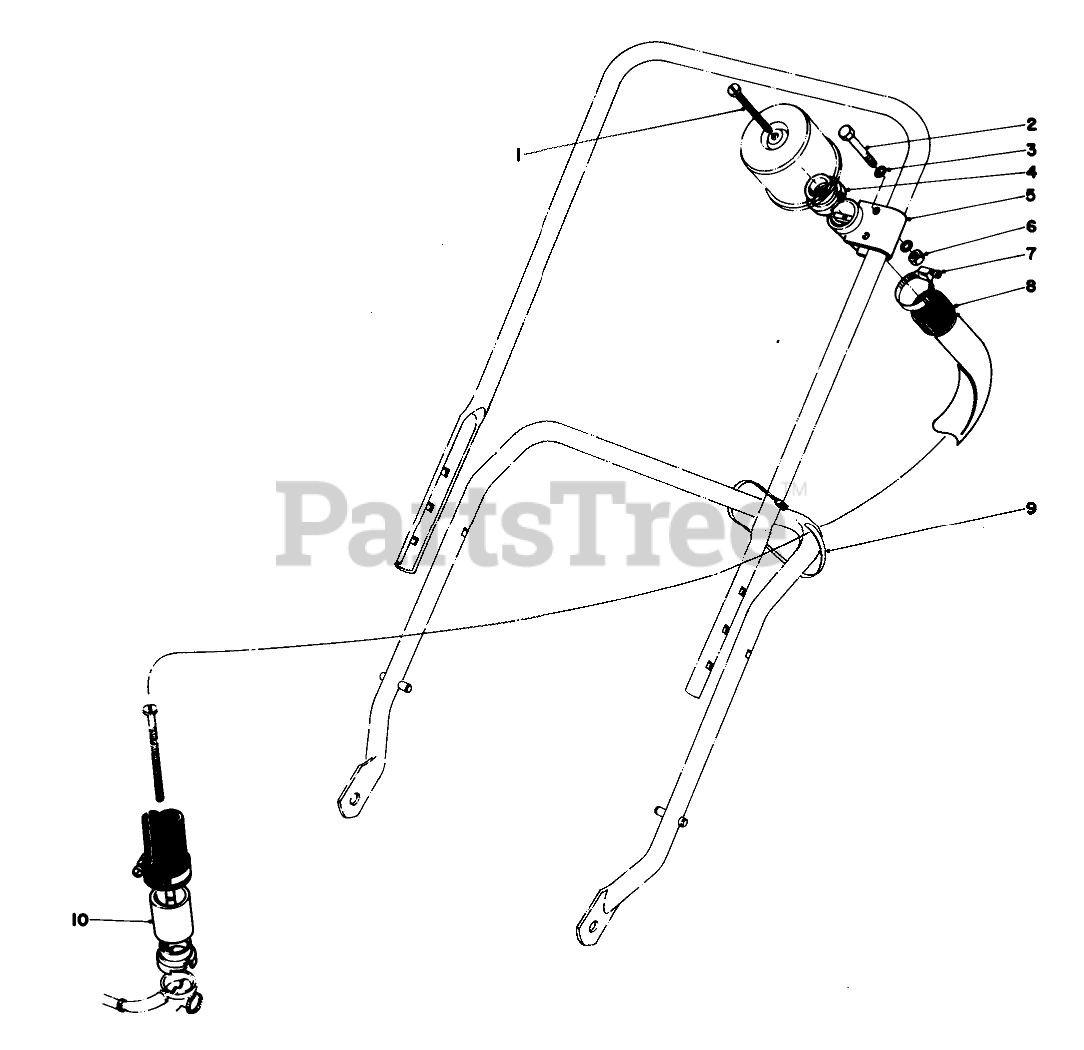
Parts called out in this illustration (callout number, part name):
1	Pan Hd. Machine Screw
2	SCREW-HH
3	WASHER-PLAIN
4	GASKET
5	Mounting Bracket Air Cleaner
6	NUT-HEX
7	CLAMP-HOSE
8	Hose Air Cleaner
9	TIE-CABLE
10	HOSE COUPLING WA B
